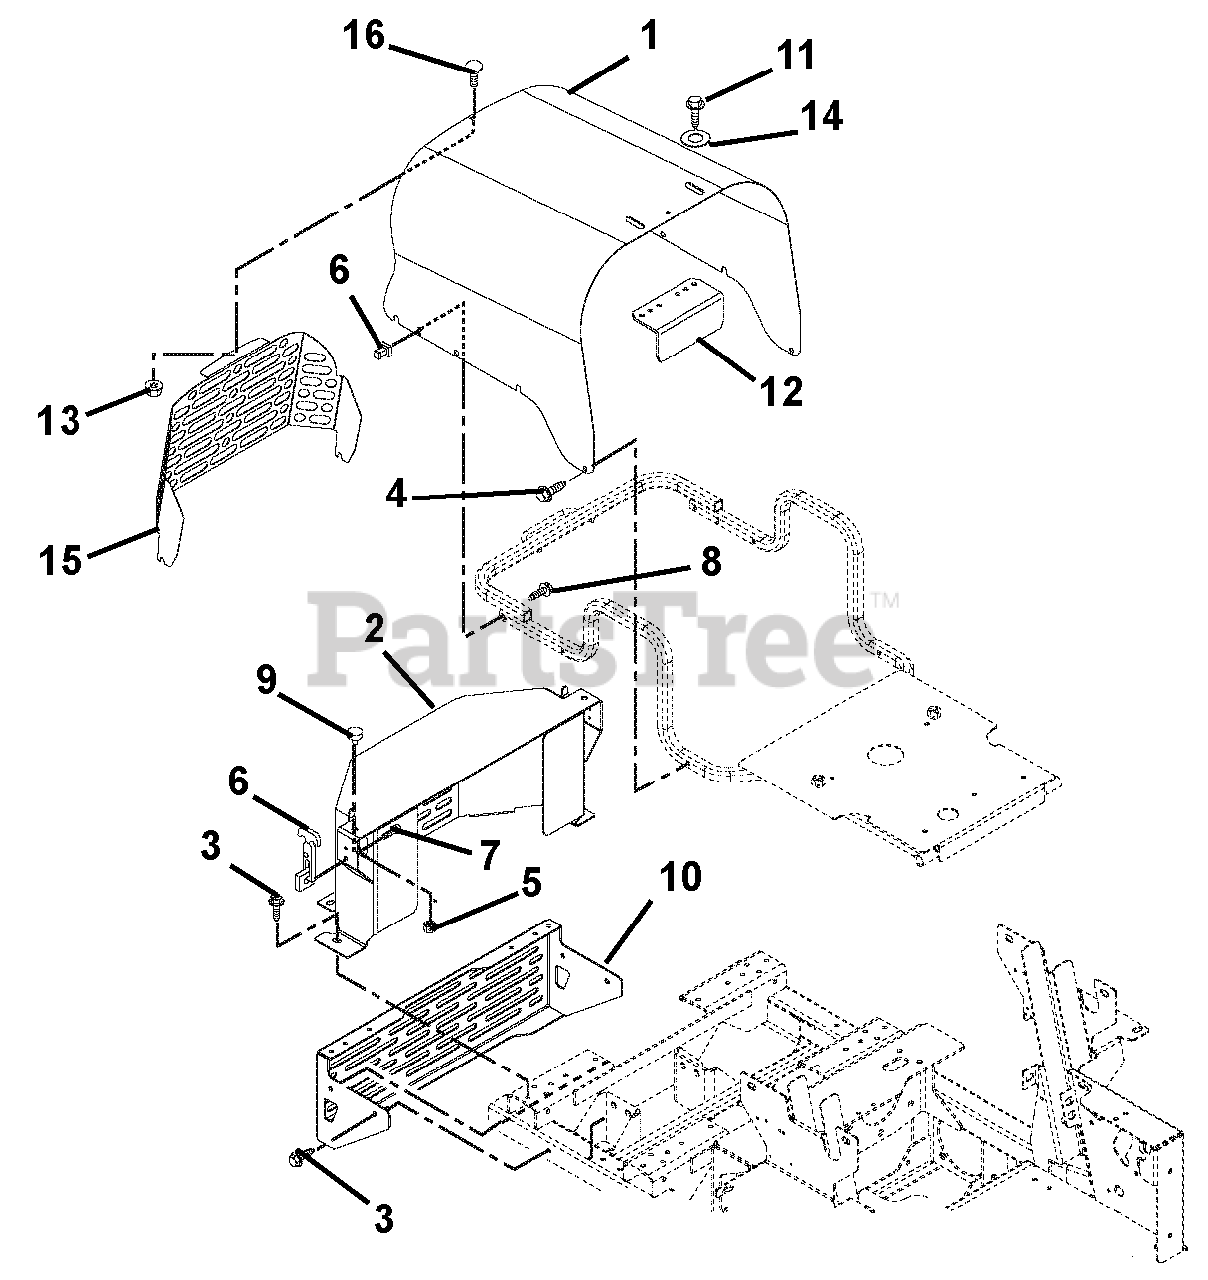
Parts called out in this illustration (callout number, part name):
1	L/C HOOD - RED
2	DIESEL BELT GUARD - BLACK
3	@SCR-TAP .38-16X.75 HWH TR YWZ
4	@SCR-TAP .38-16X.50 HWH TR YWZ
5	@NUT-SPNLK-FLG .312-18 YWZC
6	LATCH, RUBBER
7	@SCR-MCH 10-24X.50 HWH YWZC
8	@SCR-MCH 10-24X1.50 HWH YWZC
9	BUMPER, RUBBER
10	WMT, BUMPER
11	@SCR-TAP .25-20X.50 HWH TR YWZ
12	GUARD, RADIATOR CAP
13	@NUT-LK-TOP-FLG .25-20 YWZC
14	@WSHR-FL-STL.281X.62X.065 YWZC
15	L/C HOOD GUARD - BLACK
16	@BLT-RDHDSQNK .25-20X.50 G5YZ
